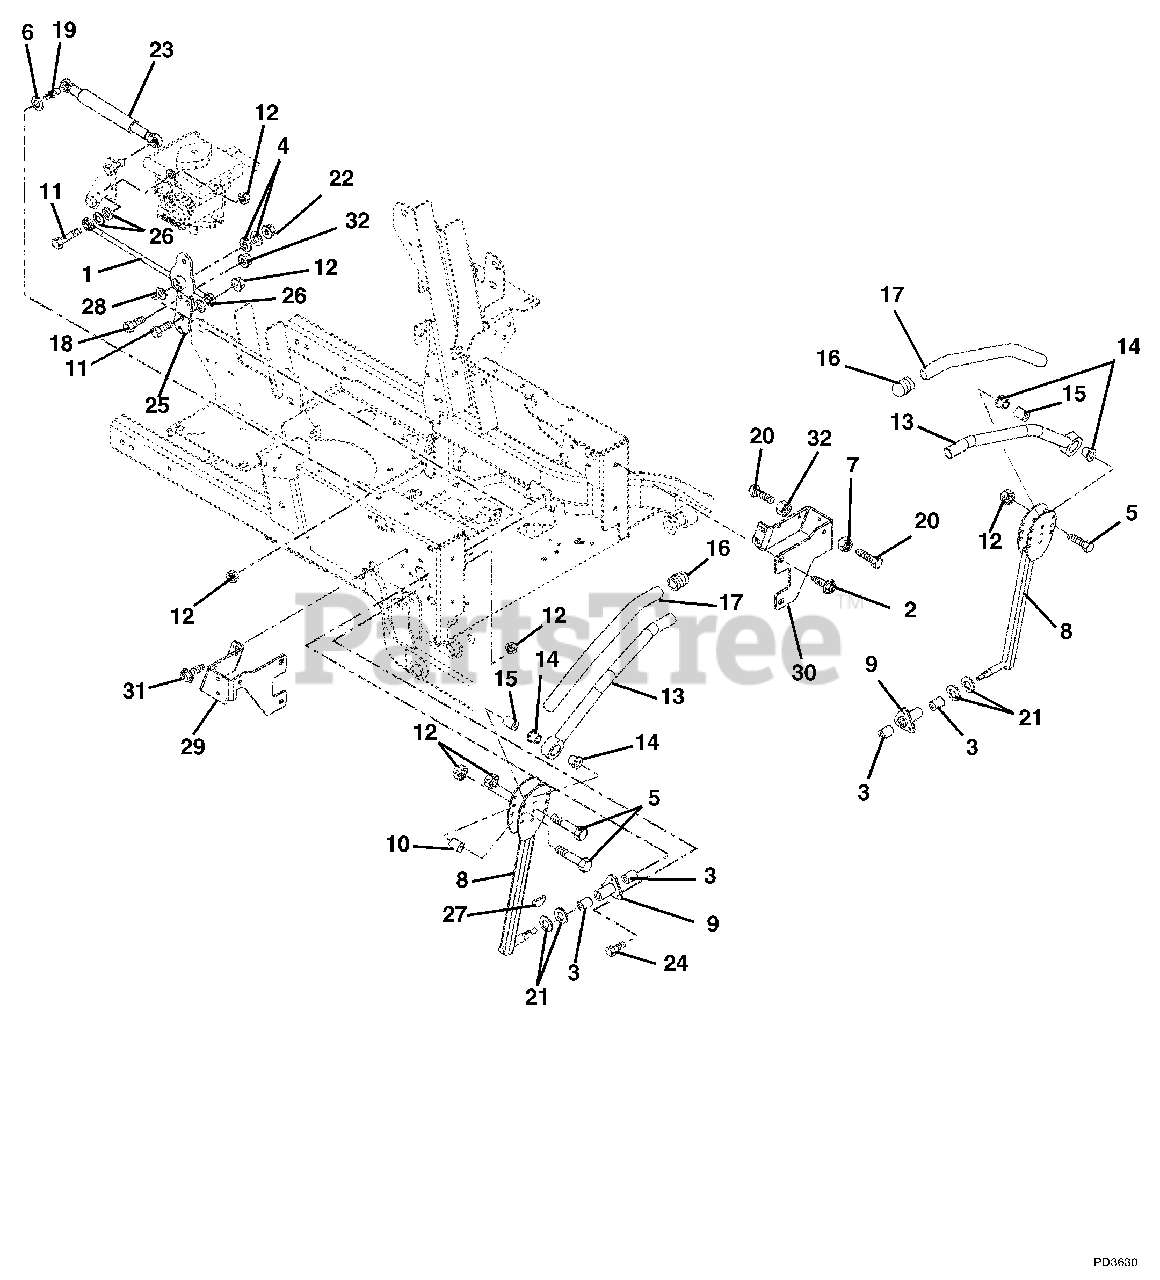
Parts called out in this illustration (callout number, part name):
1	Assembly, Steering Rod
2	Screw-Tapping .38-16 x .75 Hex Washer Head
3	Bushing .625 x .75 x .50
4	Washer-Flat-Steel .38 x .875 x .083
5	Bolt-Hex .31-18 x 1.75 Grade 5
6	Washer-Flat-Steel .344 x .688 x .065
7	Nut-Hex-Jam .375-16
8	Control Arm
9	Housing, Bushing
10	Eccentric
11	Bolt-Hex .31-18 x 1.25 Grade 5
12	Nut-Locking-Top-Flange .31-18
13	Handle Weldment Left-Hand
13	Handle Weldment Right-Hand
14	Bushing-Flange-Nylon .762 x 1.48 x .44
16	Caplug- Handlebar
17	Grip-Handlebar
18	Bolt-Hex .375-16 x 1.75
19	Stud, Ball
20	Bolt-Hex .38-16 x 1.25 Grade 5
21	Washer-Flat-Steel .63 x 1.005 x .062
22	Nut-Locking-Top-Flange .38-16
23	Dampener, Control
24	Bolt-Hex .31-18 x .75 Grade 5
25	Weldment, Pivot Arm
26	Washer-Locking .31 x .078 Regular
27	Key-Woodruff .13 x .63
28	Wave Washer
29	Stop, Steering-Right Hand
30	Stop, Steering-Left Hand
31	Screw-Tapping .38-16 x .50 Hex Washer Head
32	Nut-Locking-Jam-Center .375-16
